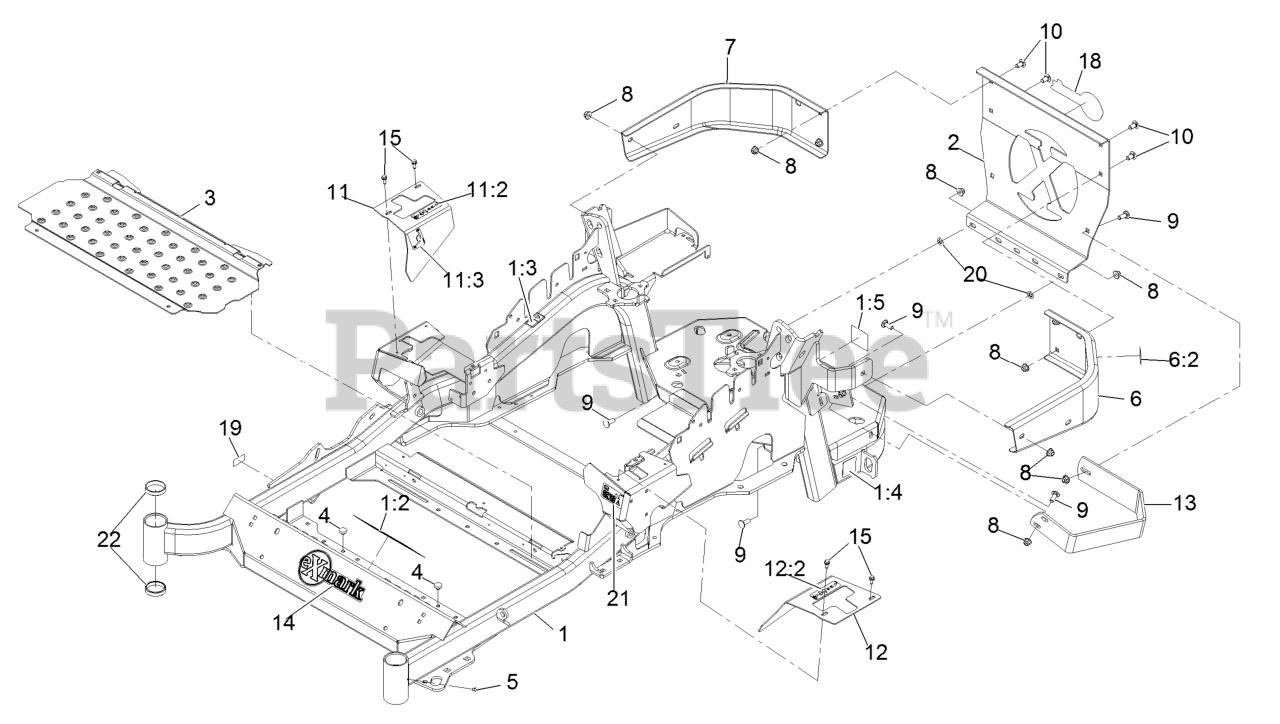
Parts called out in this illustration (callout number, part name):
1	MAINFRAME ASM
1:2	DECAL-DANGER
1:3	DECAL-WARNING
1:4	DECAL-HAZARD, PINCHED FINGER
1:5	DECAL-SPARK ARRESTER
2	PLATE,REAR GUARD
6	LH BUMPER ASM
6:2	DECAL-WARNING
7	BUMPER-RH
8	NUT-HF, NI
9	SCREW-CARR
10	SCREW-CARR
11	RH MOTION CONTROL COVER ASM
11:2	DECAL-CONTROL, MOTION
11:3	DECAL-PARK BRAKE, CE
12	LH MOTION CONTROL COVER ASM
12:2	DECAL-CONTROL, MOTION
13	GUARD-MUFFLER
14	DECAL-EXMARK LOGO
15	SCREW-HWH
18	DECAL-EXMARK LOGO
19	Decal-Patent Ttco.Com
20	NUT-PUSH
21	DECAL-FUEL FILL, CE
22	CUP-BEARING
